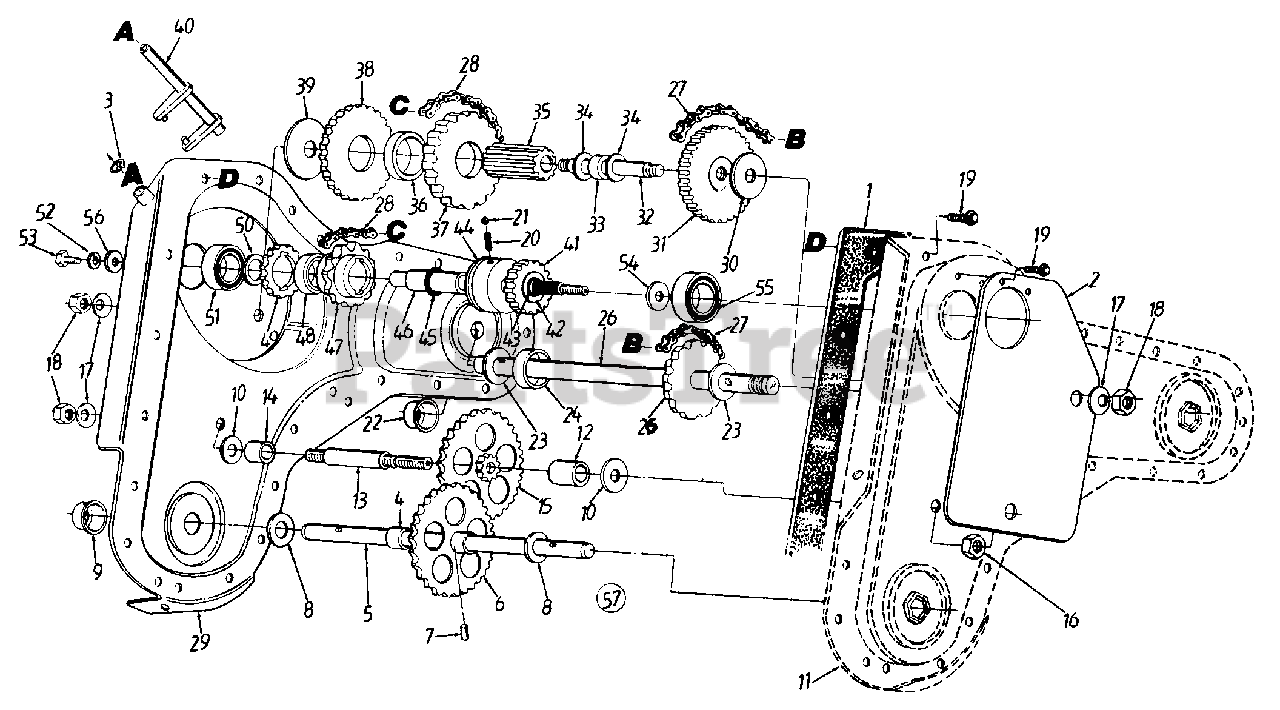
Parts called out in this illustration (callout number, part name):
1	Chain Case Gasket
3	Snap Ring
4	Spacer 735" I.D. x .886" O.D.
5	Wheel Shaft
6	Spur Gear 46T
7	Pin Type "E" Grooved
8	Fl-Wash. .76" I.D. x 1.5" O.D.
9	Dust Cover Ass'y. .75" Shaft
10	Fl-Wash. 7/16" I.D. x 1-3/8" O.D.
13	Jack Shaft 2.06" Lg.
14	Spacer .635" I.D. x 1" O.D. x .37" Thk.
15	Gear Idler Ass'y.
16	Hex Patch L-Nut 7/16-20 Thd.
17	Bell-Wash. .45" I.D. x 1" O.D.
18	Hex Nut 7/16-20 Thd.
19	Hex Wash. Hd. TT-Tap Scr. 1/4-20 x .5" Lg.
20	Spring Detent
21	Ball Detent
22	Dust Cover Ass'y. 1" Shaft
23	Thrust Wash. 1.03" I.D. x 1.62" O.D.
24	Spacer 1" I.D. x 2" O.D. x .5" Thk.
26	tine Shaft Ass'y.
27	Chain - #50 5/8" Pitch x 52 Links - Endless
28	Chain - #41 1/2" Pitch x 30 Links - Endless
30	Ft-Wash. 7/16" I.D. x 1-3/8" O.D.
31	Gear and Sprocket Ass'y.
32	Jack Shaft 5" Lg.
33	Spacer .636" I.D. x .86" O.D.
34	Fl-Wash. .63" I.D. x .94" O.D.
35	Spur Gear 10T
36	Spacer 1.5" I.D. x 1.76" O.D.
37	Sprocket - #41 Chain
38	Reverse Gear 46T
39	Thrust Wash. .445" I.D. x 1.92" O.D.
40	Shifter Ass'y.
41	Spur Gear 17T
42	Fl-Wash. .69" I.D. x 1.06" O.D.
43	Retaining Ring .669" Shaft
44	Clutch Collar
45	Retaining Ring .875" Shaft
46	Drive Shaft
47	Sprocket 11T
48	Neutral Spacer
49	Spur Gear 16T
50	Fl-Wash. 5/8" I.D. x 1" O.D.
51	Ball Bearing .669" I.D.
52	L-Wash. 1/4" I.D.
53	Hex Bolt 1/4-20 x .62" Lg.
54	Fl-Wash. .635" I.D. x 1" O.D.
55	Ball Bearing
56	Fl-Wash. .281" I.D. x .875" O.D.
57	Gear Case Ass'y. Comp.
